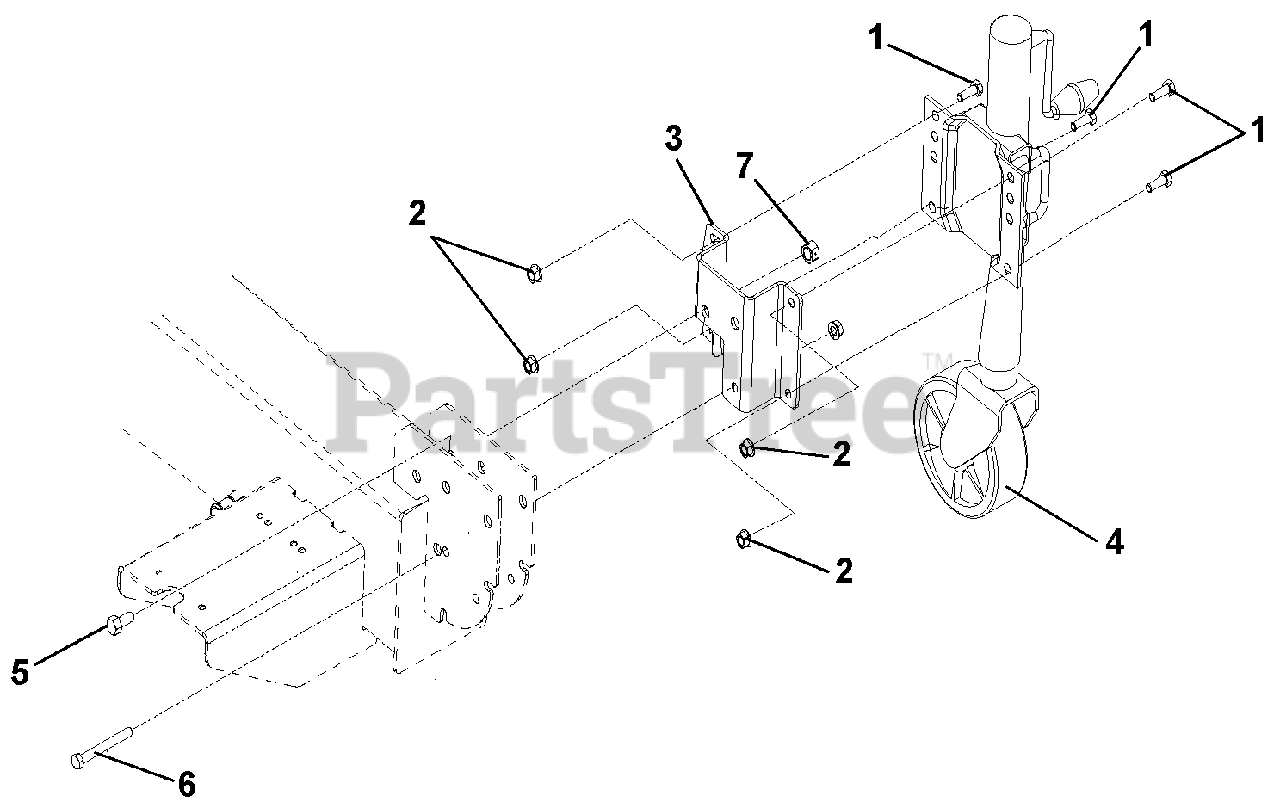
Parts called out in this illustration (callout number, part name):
1	@BLT-HEX .38-16X1.00 GR5 YWZC
2	@NUT-LK-TOP-FLG .38-16 YWZC
3	BRACKET, MOUNTING
4	STAND, JACK-W/WHEEL
5	@BLT-HEX .50-13X1.00 GR5 YWZC
6	@BLT-HEX .38-16X3.25 GR5 YWZC
7	NUT-LK-CTR-FLG .50-13 YWZC
